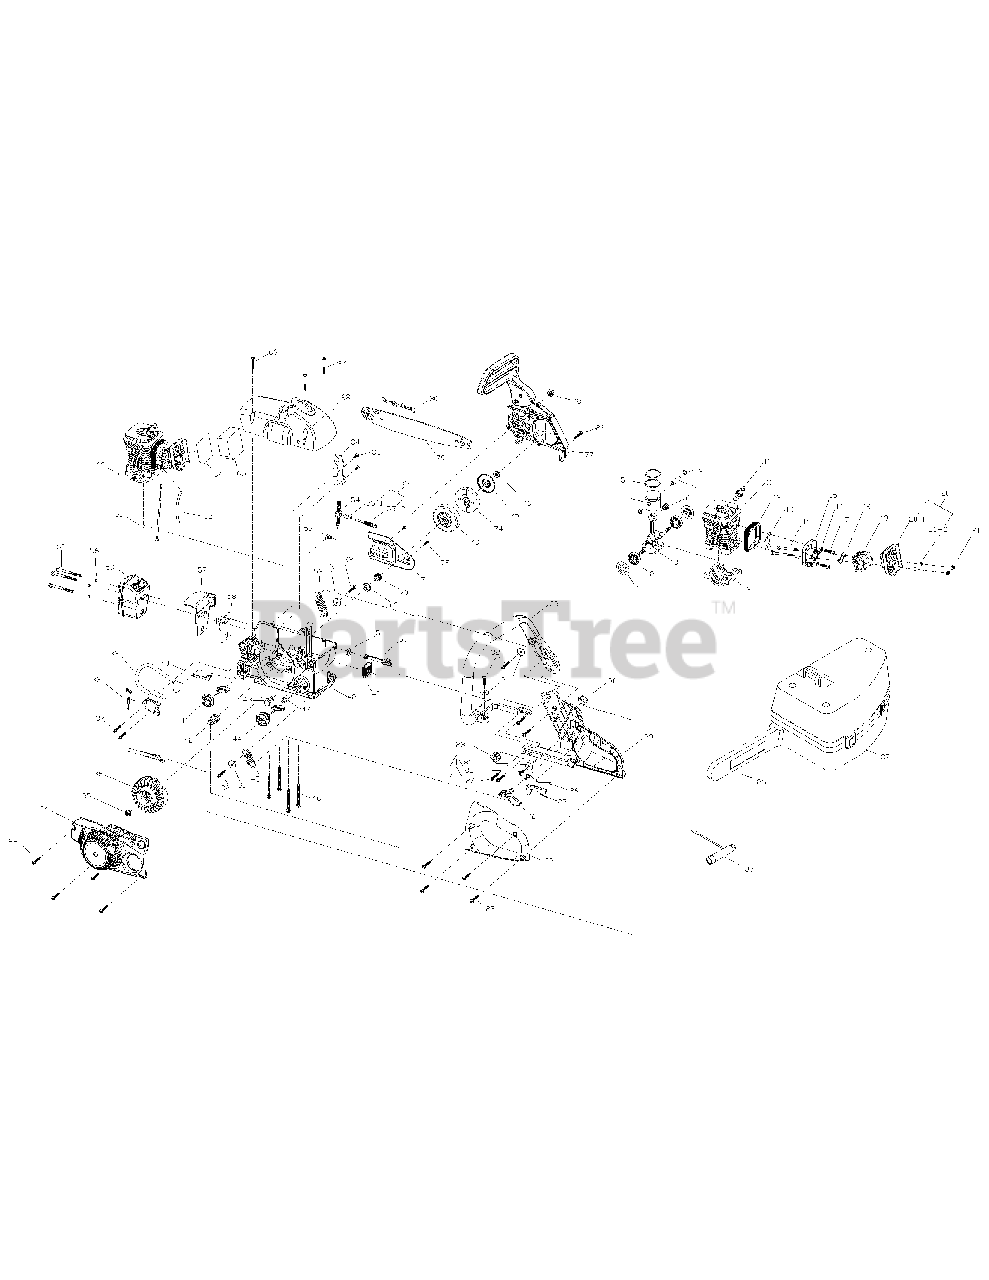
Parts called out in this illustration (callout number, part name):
1	Cap, Bearing
3	Crank/Rod Assembly
5	Ring, Piston
6	Roller, Piston
7	Pin, Piston
8	Ring, Piston
9	Case, Crank
10	Spark Plug
12	Rubber, Isolator
15	Isolator, Carburetor
16	Spring Washer
19	Carburetor
20	Air Filter Assembly
23	Handle, Left Part
24	Trigger, Throttle
25	Trigger Release
28	Rubber, Isolator
33	Handle, Front
34	Starter Housing Assembly
38	Wire Assembly
39	Ignition Assembly
40	Conductive Plate
41	Oil Cap Assembly
42	Spring Assembly
44	Fuel Cap Assembly
48	Housing Assembly
49	Holder, Cable
50	Lever, Choke
51	Holder, Choke Level
55	Pump Assembly
56	Spring Washer
59	Muffler Assembly
61	Cable, Throttle
62	Fuel Pipe
63	Woodruff Key
65	Filter, Air
71	Cap, Anti-Dust
73	Drum Assembly
74	Clutch Assembly
75	Cap, Anti-Dust
77	Brake Kit Assembly
80	18'' Chain
80	16'' Chain
84	Spiked Bumper
87	Carry Case
